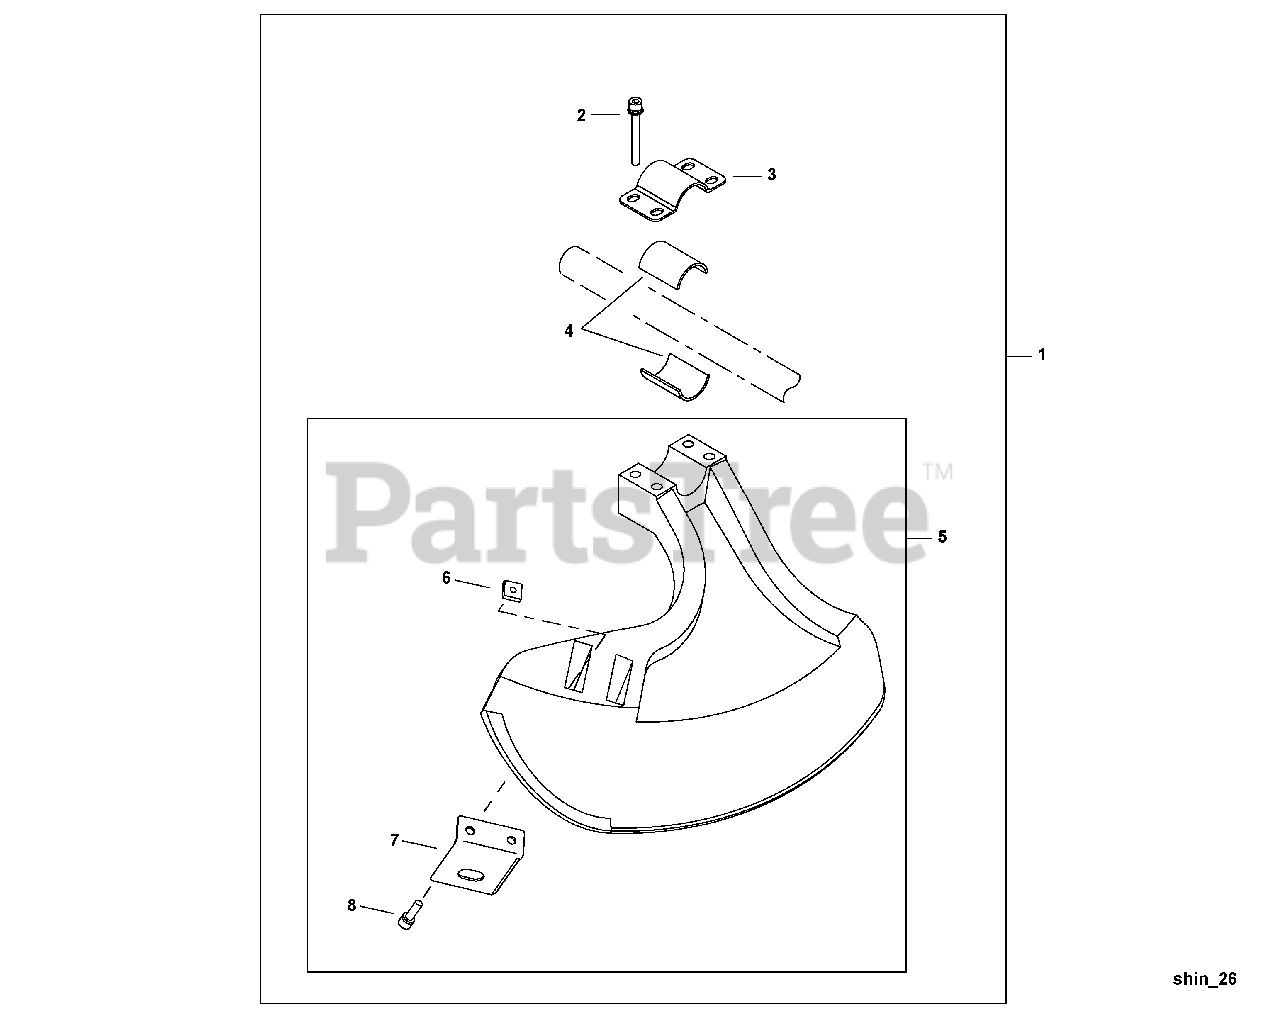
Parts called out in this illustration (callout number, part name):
1	DEBRIS SHIELD KIT
2	SCREW - 5X45
3	CLAMP - UPPER
4	SPACER
5	DEBRIS SHIELD ASSY
6	NUT - 5
7	KNIFE, TRIMMER LINE
8	SCREW - 5X16
